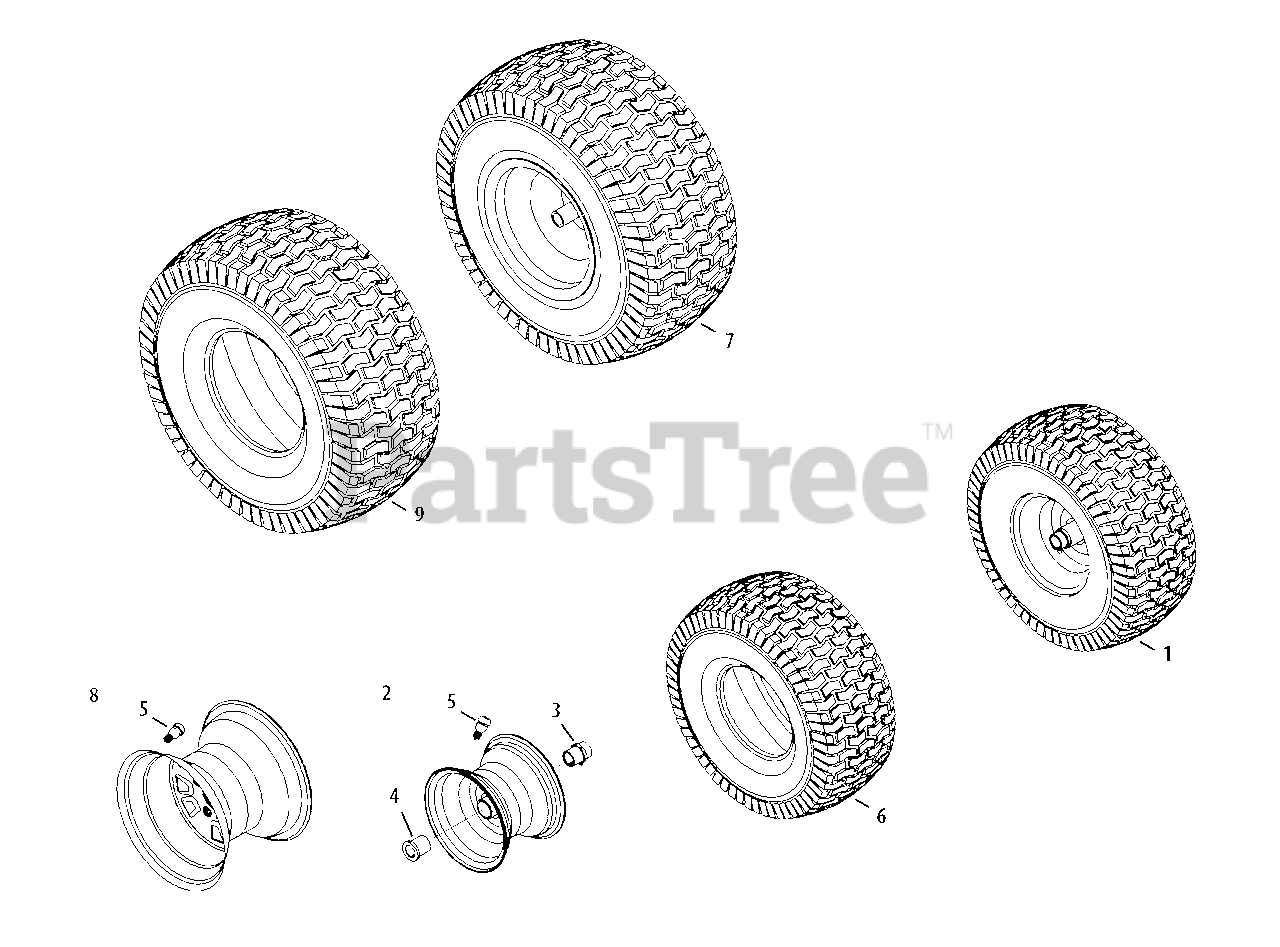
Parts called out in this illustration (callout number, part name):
1	Wheel Ass’y, Complete, 16 x 6 x 5.8
2	Rim Ass’y, 8.0 x 5.3, Flange Bearings
3	Bearing, Flange, .760 ID w/ Fitting
4	Bearing, Flange, .760 x 1.00 x 1.20
5	Valve, Tubeless Air
6	Tire, 15 x 6.5 x 8 Sq Shoulder
7	Wheel, Complete, 22 x 9.5 x 12
8	Rim Ass’y, 12.0 x 7.0
9	Tire, 22 x 9.5 x 12 Sq Shoulder
